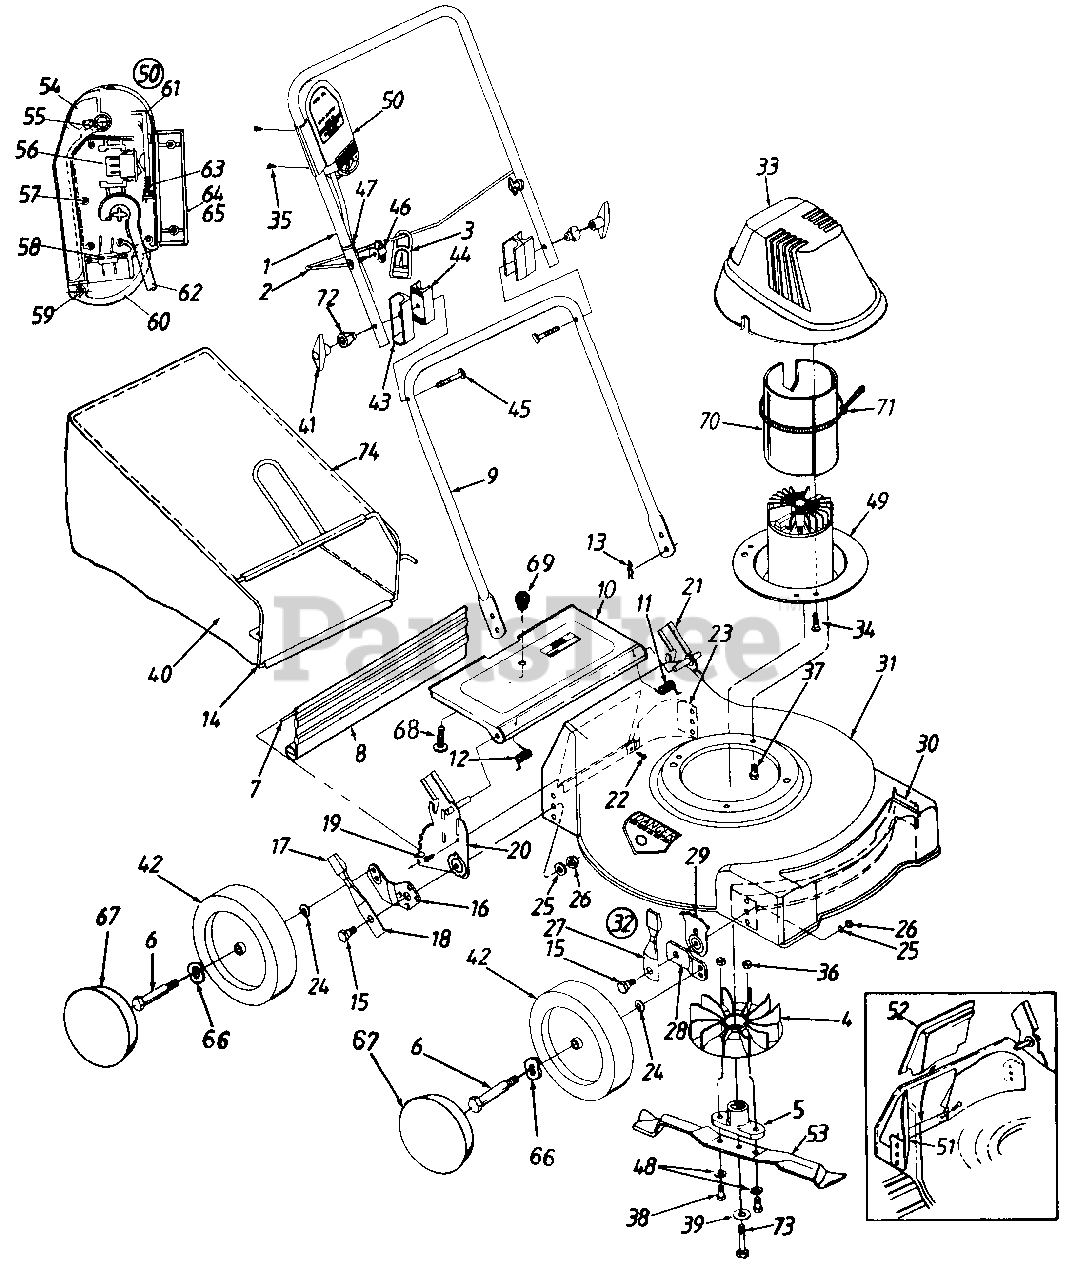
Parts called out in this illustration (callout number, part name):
3	Strain Relief-Cord
5	Blade Adapter
6	Axle Bolt
7	Rear Flap Wire
8	Rear Flap
9	Lower Handle
12	Door Spring-R.H.
13	Hairpin Clip
16	Pivot Bar-R.H.
17	Spring Lever Knob
18	Spring Lever
19	Hex L-Wash. Hd. AB-Tap Scr. 1/4 x .62" Lg.
22	Torx. Mach. AB-Tap Scr. 1/4 x .62" Lg.
23	Rear Baffle
24	Bell-Wash. .38" I.D. x .88" O.D.
25	Bell-Wash. .39" I.D. x 1.38" O.D.
26	Hex Nut 3/8-16 Thd.
27	Spring Lever Ass'y. w/Knob
29	Height Adj. Plate
33	Motor Cover
34	Scr. #10-16 x .75" Lg.
35	Self-Tap. Scr. #7 x 1" Lg.
36	Hex Nut 3/8-24 Thd.
37	Hex L-Wash. TT-Tap Scr. 3/8-16 x .75" Lg.
38	Hex Bolt 3/8-24 x 1.25" Lg.
39	Bell-Wash. .396" I.D. x 1.14"
40	Grass Bag
41	Plastic Knob
42	Wheel Ass'y. Comp.
43	Upper Handle Insulator
44	Lower Handle Insulator
45	Carriage Bolt 5/16-18 x 3.25"
46	Wing Nut 1/4-20 Thd.
47	Cable Tie
48	Bell-Wash. 3/8" I.D.
49	Motor, Cord & Switch Ass'y.
50	Cord & Switch Ass'y. Comp.
53	19" Mulching Blade
54	Handle-Switch Actuator
55	Spring-Switch Handle
56	Switch
57	Screw #6-32 x .5" Lg.
58	Plug Ass'y.
59	Retainer Plug Spring
60	Retainer Plug
62	Cord Ass'y.
63	Spring Latch
64	Housing-Upper Half
66	Wave Wash. .51" I.D.
67	Hub Cap
68	Truss Scr. #10-24 x .38" Lg.
70	Insulator
71	Cable Tie
72	Insulator Knob
73	Hex Bolt 3/8-24 x 2.5" Lg.
